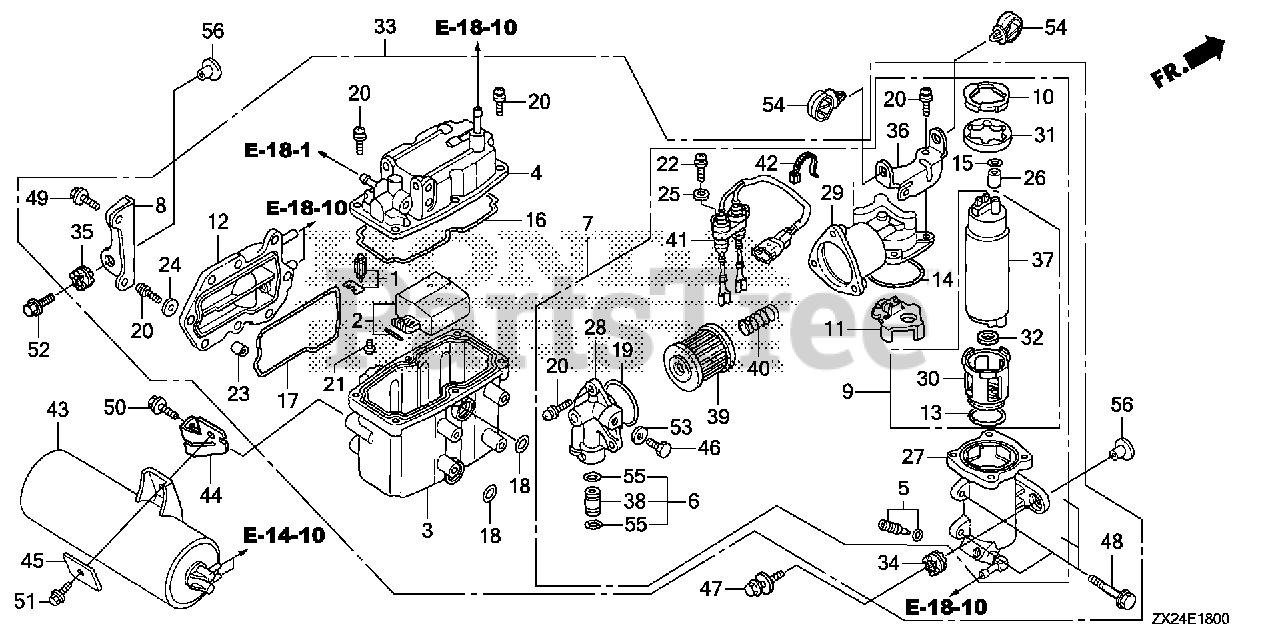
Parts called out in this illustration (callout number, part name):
1	VALVE SET, FLOAT
3	BODY
5	SCREW SET, DRAIN
7	PUMP UNIT SET A, FUEL (MSDS)
8	STAY, PLATE
9	PUMP UNIT SET B, FUEL (MSDS)
12	COVER, WATER JACKET
15	O-RING
15	O-RING (7.3X2.2) (NOK)
20	SCREW-WASHER
21	SCREW, PAN
22	SCREW, WASHER
23	COLLAR, SET
24	WASHER, PLAIN
25	WASHER, PLAIN
27	CASE, PUMP
28	COVER, PUMP
29	COVER, PUMP (A)
33	SEPARATOR ASSY., VAPOR
34	GROMMET, VAPOR SEPARATOR
35	GROMMET, VAPOR SEPARATOR
36	STAY, PLATE
37	PUMP UNIT, FUEL (MSDS)
38	JOINT, FUEL PIPE
39	SCREEN, FUEL STRAINER
40	SPRING, SET
43	TANK, VACUUM
44	STAY, VACUUM TANK
46	BOLT, SEALING (6MM)
47	BOLT-WASHER (8X35)
48	BOLT, FLANGE (6X25)
49	BOLT, FLANGE (6X16)
50	BOLT, FLANGE (6X14)
51	BOLT, FLANGE (6X12)
52	BOLT, FLANGE (8X35)
53	WASHER, SEALING (6MM)
54	CLIP, HARNESS
55	O-RING (7.8X1.9) (ARAI)
56	COLLAR (8.5X14.5)
